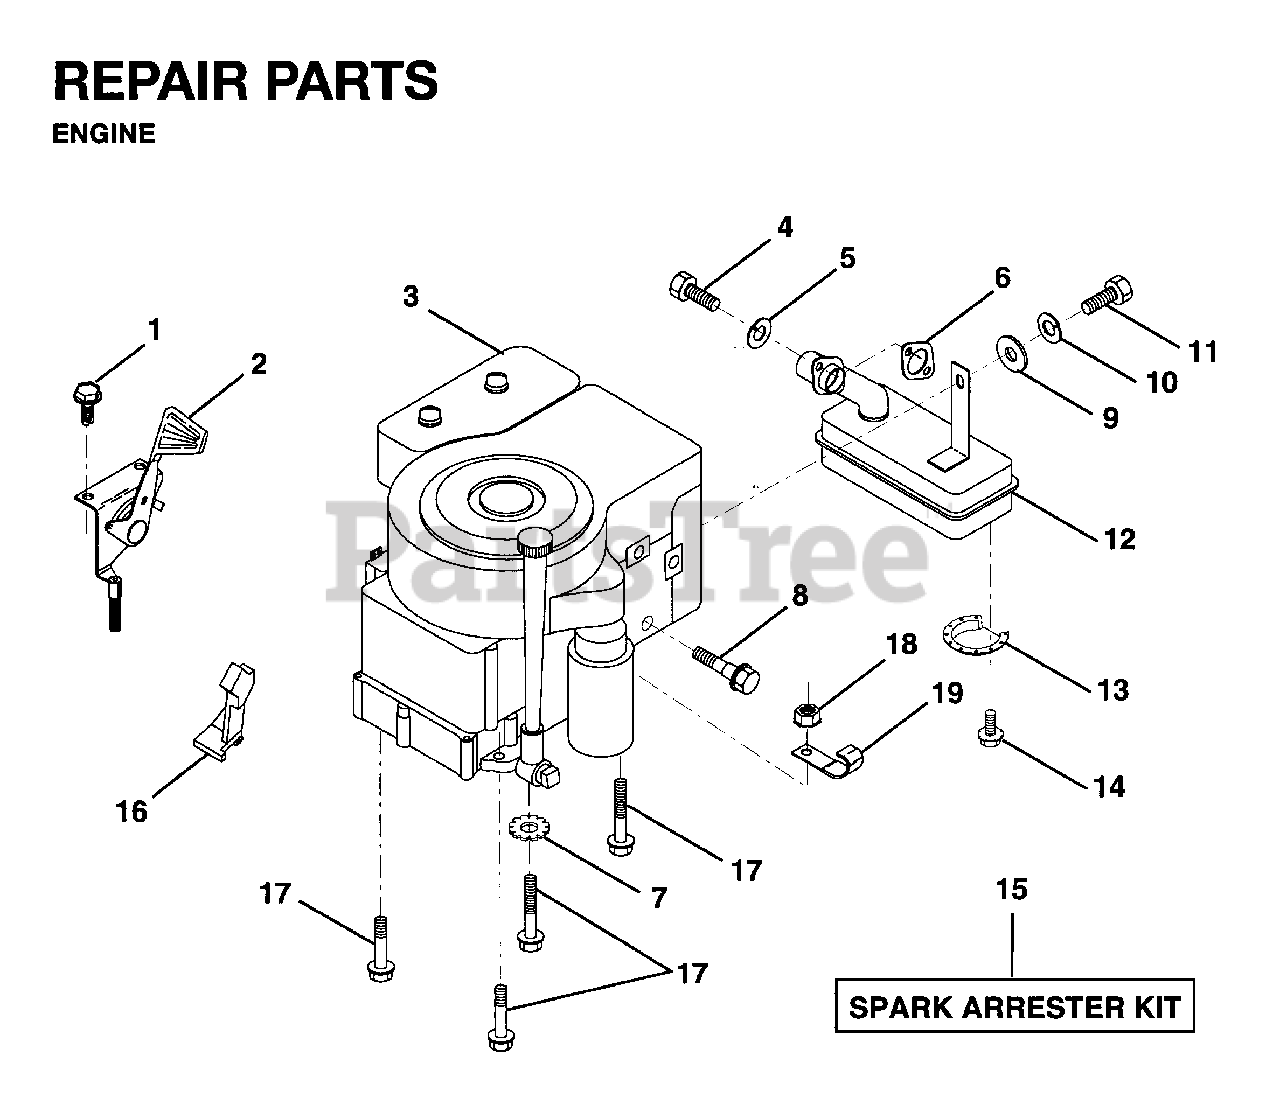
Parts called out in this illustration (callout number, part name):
2	THROTTLE CONTROL
4	SCREW
5	LOCKWASHER
6	GASKET ENGINE
7	WASHER, LOCK 3/8
9	WASHER - 26X6.5X1.6
10	LOCKWASHER
13	DEFL MUFFLER LTV
14	SCREW
15	ARRESTER SPARK (OPTIONAL)
16	STOP THROTTLE
17	BOLT
18	NUT.HEX.3/8-16UNC
19	CLIP T
